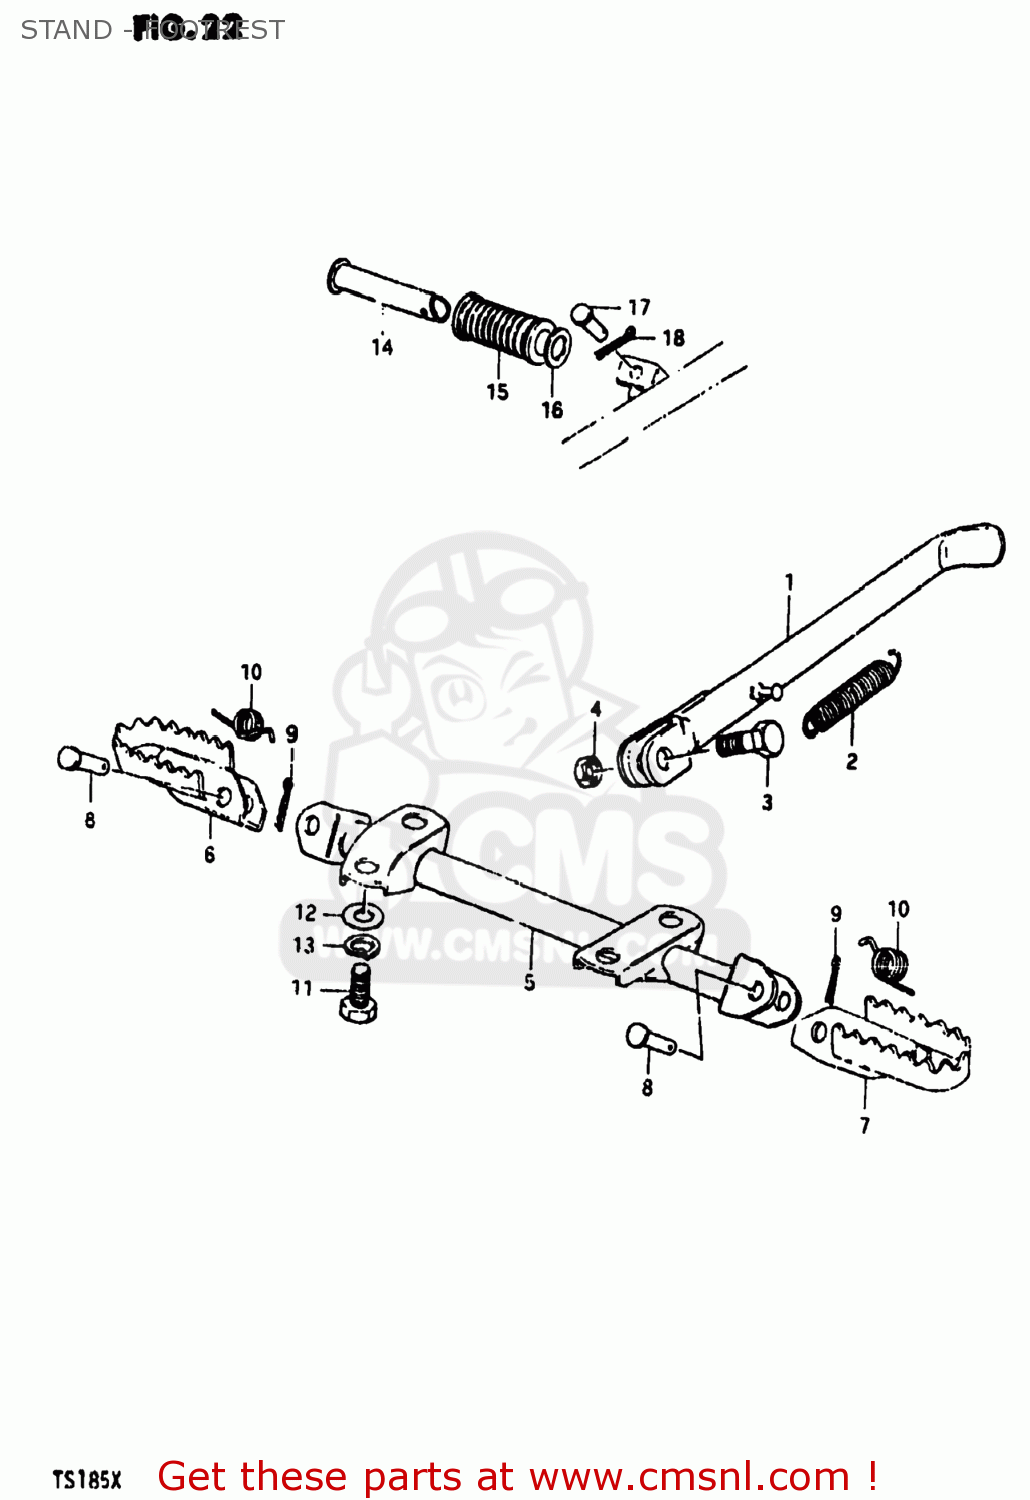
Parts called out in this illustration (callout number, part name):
1	STAND,PROP
2	SPRING
3	BOLT(10X30)
4	NUT
5	BAR,FR FOOTREST
6	FOOTREST,FR,R
7	FOOTREST,FR,L
8	PIN
9	PIN 20X20
10	SPRING
11	BOLT
12	WASHER
13	WASHER,LOCK,8.
14	BAR,FOOTREST RUBBER
15	RUBBER,PILLION FOOTREST
16	WASHER (19.5X32X2)
17	PIN
18	PIN 20X20
